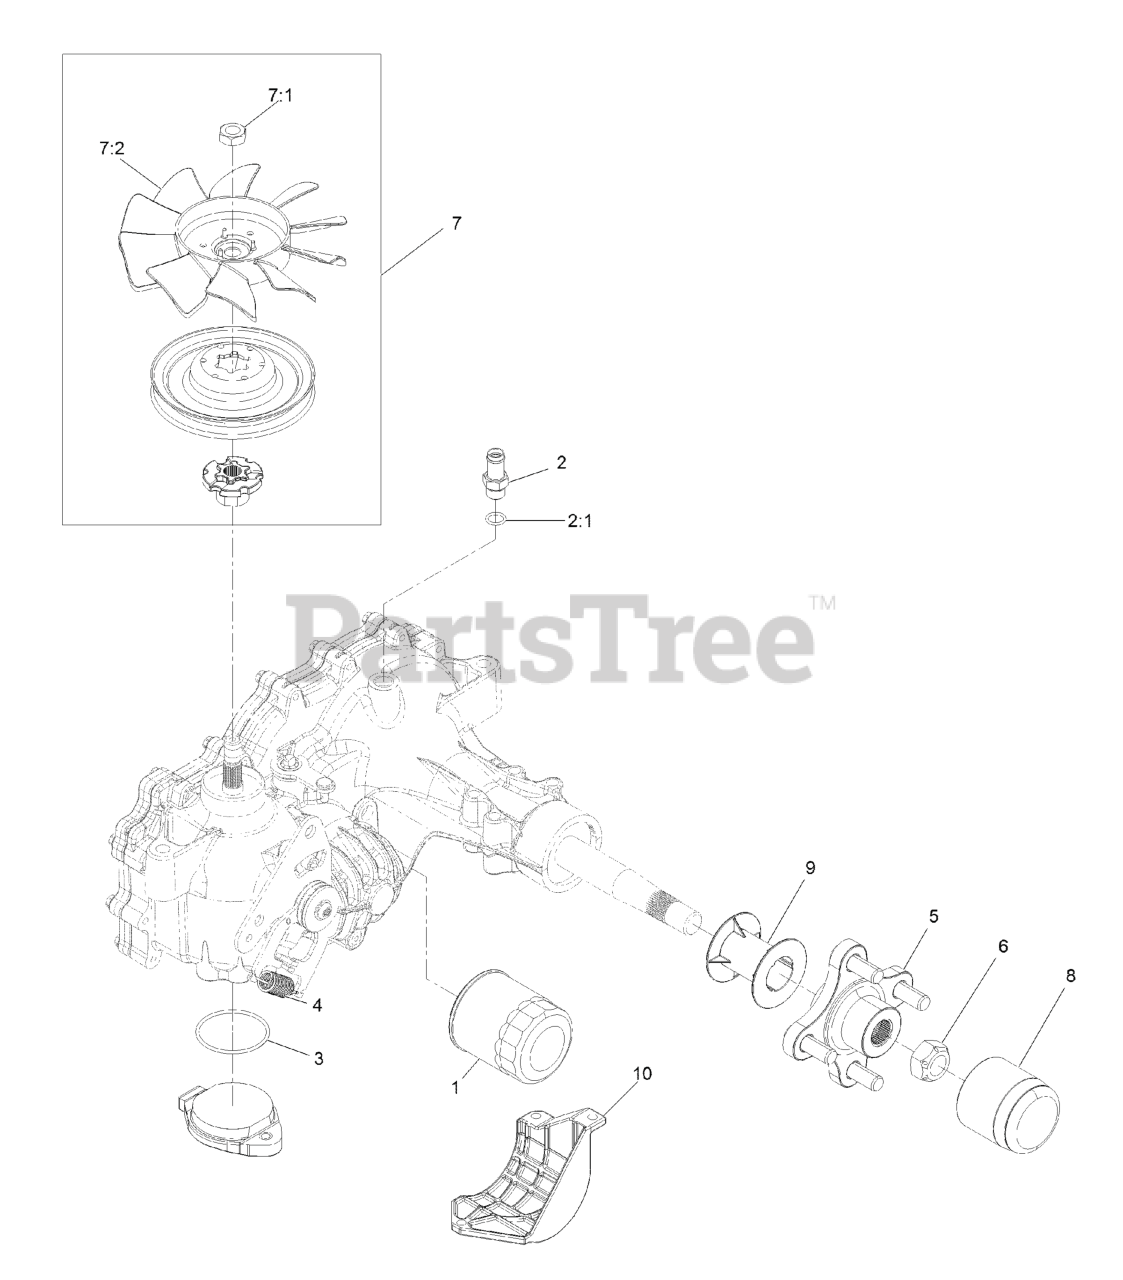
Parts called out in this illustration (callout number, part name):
1	ELEMENT-OIL FILTER, HYD
2	ADAPTER-STRAIGHT
2:1	O-RING
3	O RING-SEAL
4	SPRING-EXTENSION
5	HUB-OFFSET
6	NUT-HUB
7	Fan And Pulley Kit
8	CAP-AXLE, LONG
9	TUBE-AXLE
10	GUARD-FILTER, LH
99	BRAKE SHAFT SEAL KIT
